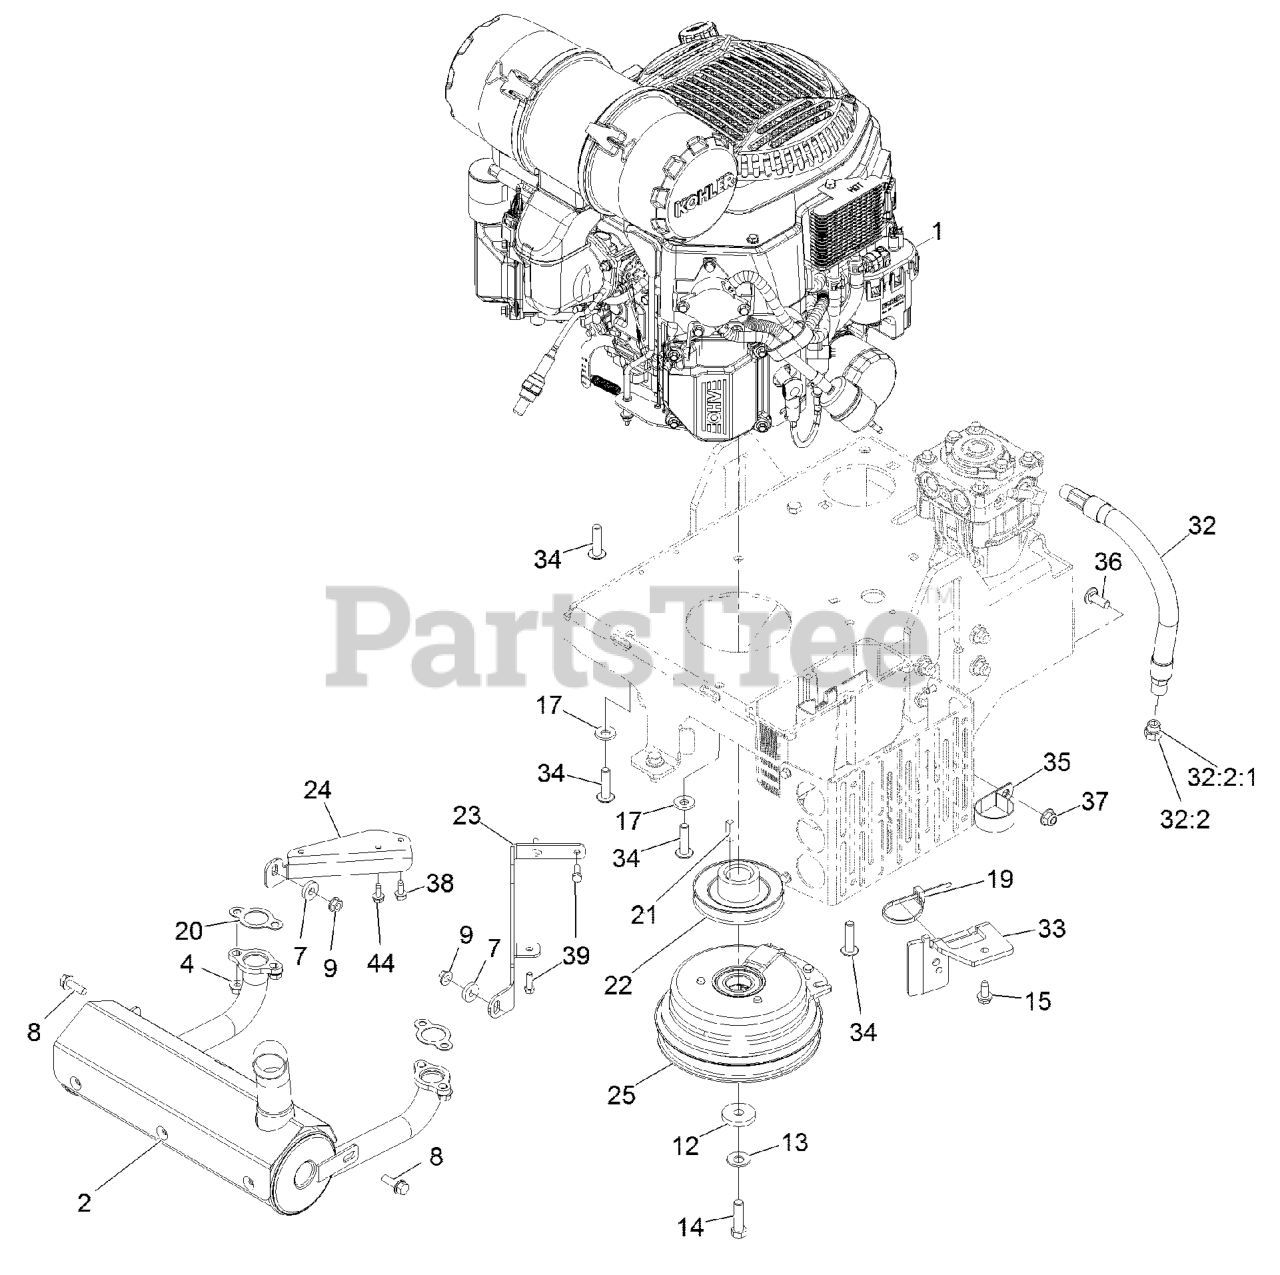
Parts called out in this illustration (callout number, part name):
4	NUT-FLANGE
8	SCREW-HHF
12	WASHER
13	WASHER-SPRING
14	SCREW-HH
15	Screw-HWH 5/16-18 X 3/4 Tf
17	WASHER-BELLEVILLE
19	TIE-CABLE
20	GASKET-EXHAUST
23	MOUNT, MUFFLER-LT
24	MOUNT, MUFFLER-RT
25	CLUTCH-200 FT-LB, 1.125 B
32	OIL DRAIN HOSE ASM
32:2	PLUG-HH
32:2:1	O-RING
33	BRACKET-ANCHOR, CLUTCH
34	SCREW-BHTF
35	CLAMP-R
36	SCREW-CARR
37	NUT-HF, NI
38	SCREW-HWHTF
39	SCREW-HH M6-1 X 20Mm W/Patch
44	SCREW-HWHTF
